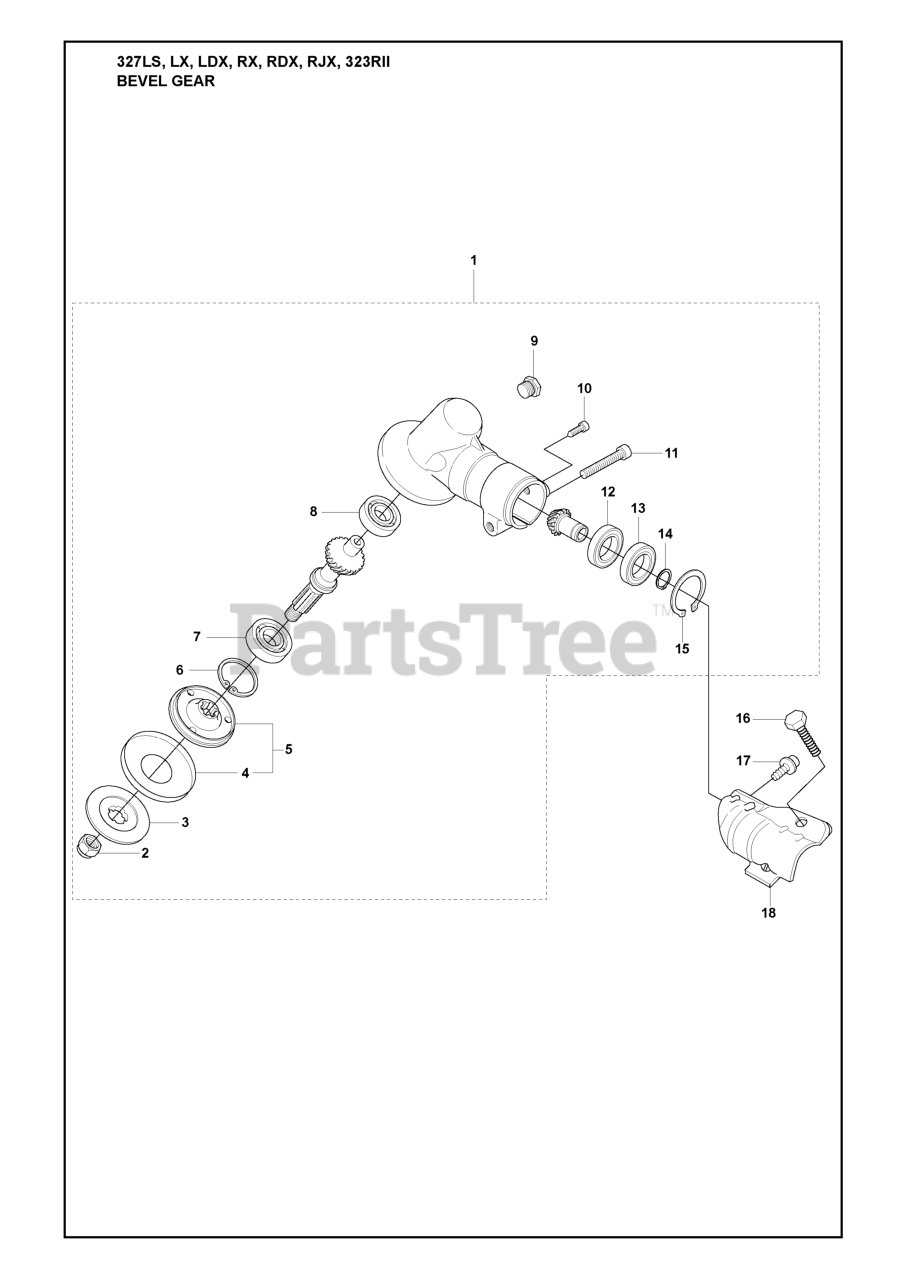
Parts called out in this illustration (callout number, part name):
1	GEAR HEAD
2	GEARHEAD NUT - BRUSHCUTTER
3	SUPPORT FLANGE
4	WASHER
5	DRIVE DISC
6	RETAINING RING SGH 28
7	BEARING
8	BALL BEARING 8X22X7/608Z
12	BALL BEARING 24X9X1/609ZR
14	RETAINING RING
15	RETAINING RING
16	SCREW M6S 6X20
18	RP BRACKET TRIMMER GUARD
